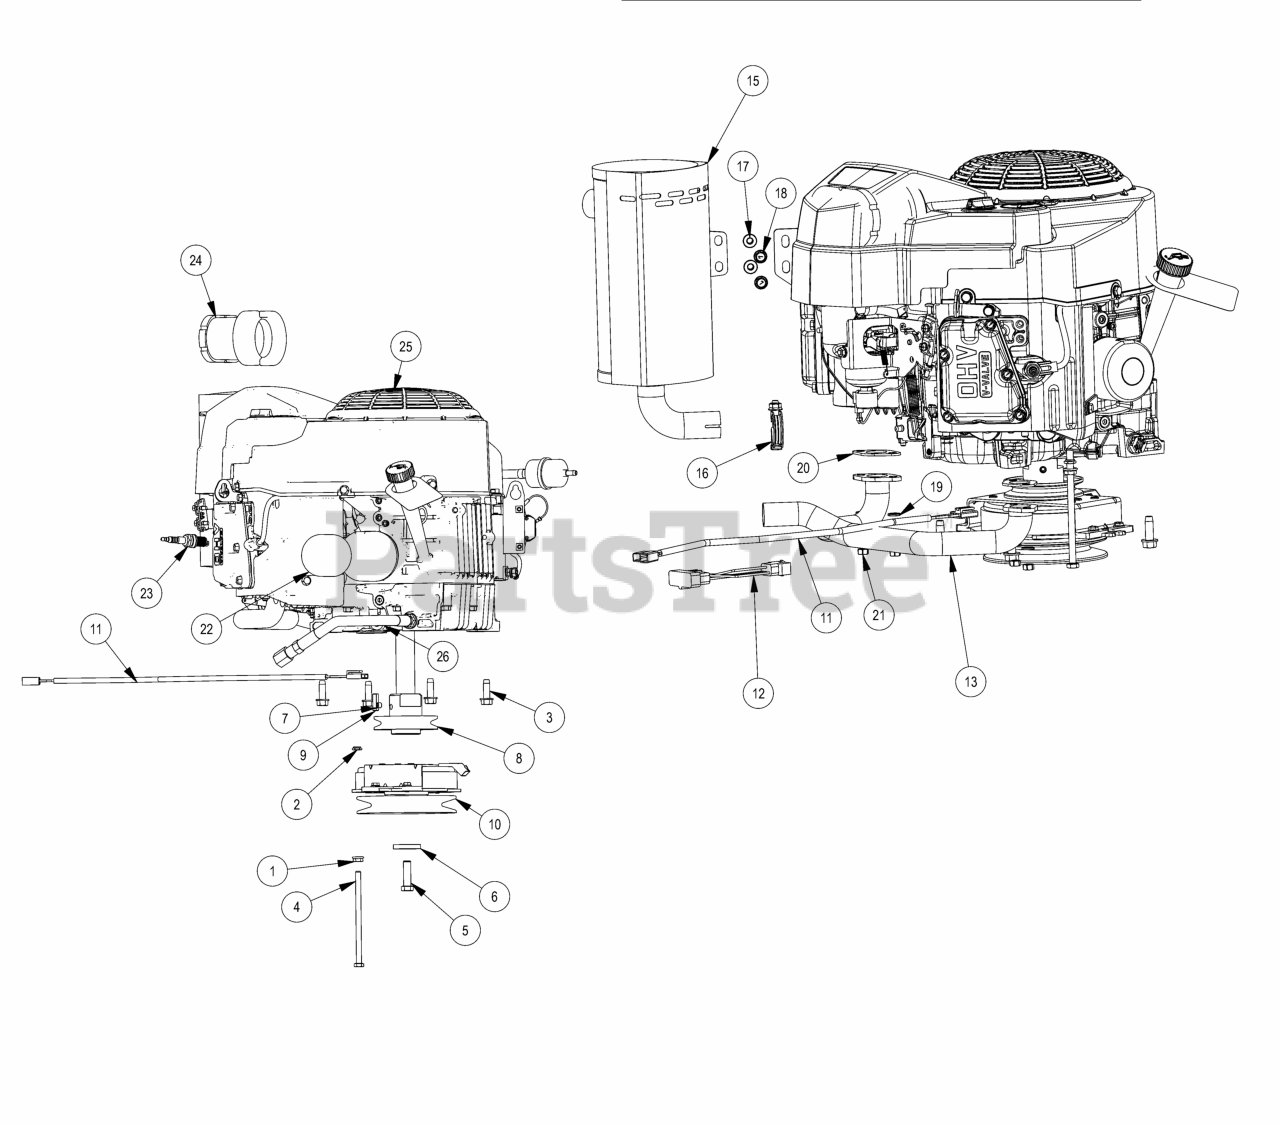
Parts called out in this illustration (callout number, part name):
1	5/16-18 HEX SERRATED FLANGE NUT HARD/ZINC
2	5/16-18 Nylock Jam Nut
3	3/8-16 X 1-1/8 HEX WASHER UNSLOT SERRATED (TRI-LOB) TRS ZINC YELLOW
4	5/16-18 X 5-1/2 HEX CAP SCREW (GR.5) ZINC
5	7/16-20 X 1-1/2 HEX CAP SCREW (GR.8) w/ Patch
6	CLUTCH WASHER
7	5/16 Set Screw
8	3-3/4" Motor Pulley SD
9	1/4" x 1" Key
11	Clutch Pigtail
12	2019 Harness Adaptor-Gen2 FX-ALL
13	Exhaust Pipe
14	Exhaust Bracket
16	Exhaust Clamp
17	Exhaust Nut
18	Exhaust Flange Bolt
19	Exhaust Lock Washer
20	Exhaust Gasket
21	M8-1.25 Zinc Nut
22	Oil Filter
23	Spark Plug - Kawasaki
24	Kawasaki Air Filter
25	Kawasaki 18.5HP FS600 Electric Start
26	Oil drain Hose
